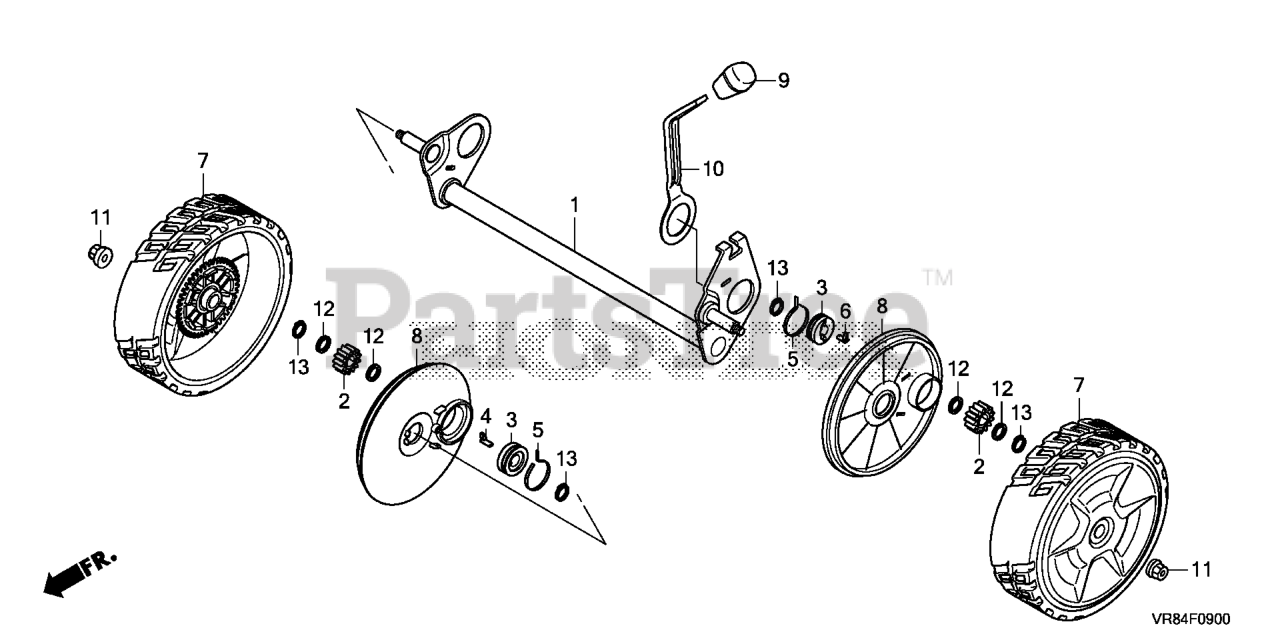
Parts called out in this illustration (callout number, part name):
1	SHAFT, RR. AXLE
2	GEAR, PINION (13T)
3	HOLDER, RATCHET
4	RATCHET (R)
5	SPRING, RATCHET RETURN
6	RATCHET (L)
7	WHEEL, RR. *NH105* (MAT BLACK)
9	GRIP, ADJUSTER *NH164* (GRIP GRAY)
10	PLATE, RR. ADJUSTER
11	NUT, FLANGE (8MM)
12	WASHER (12.8X17.5X1.0)
13	CIRCLIP (OUTER) (12.7MM)
